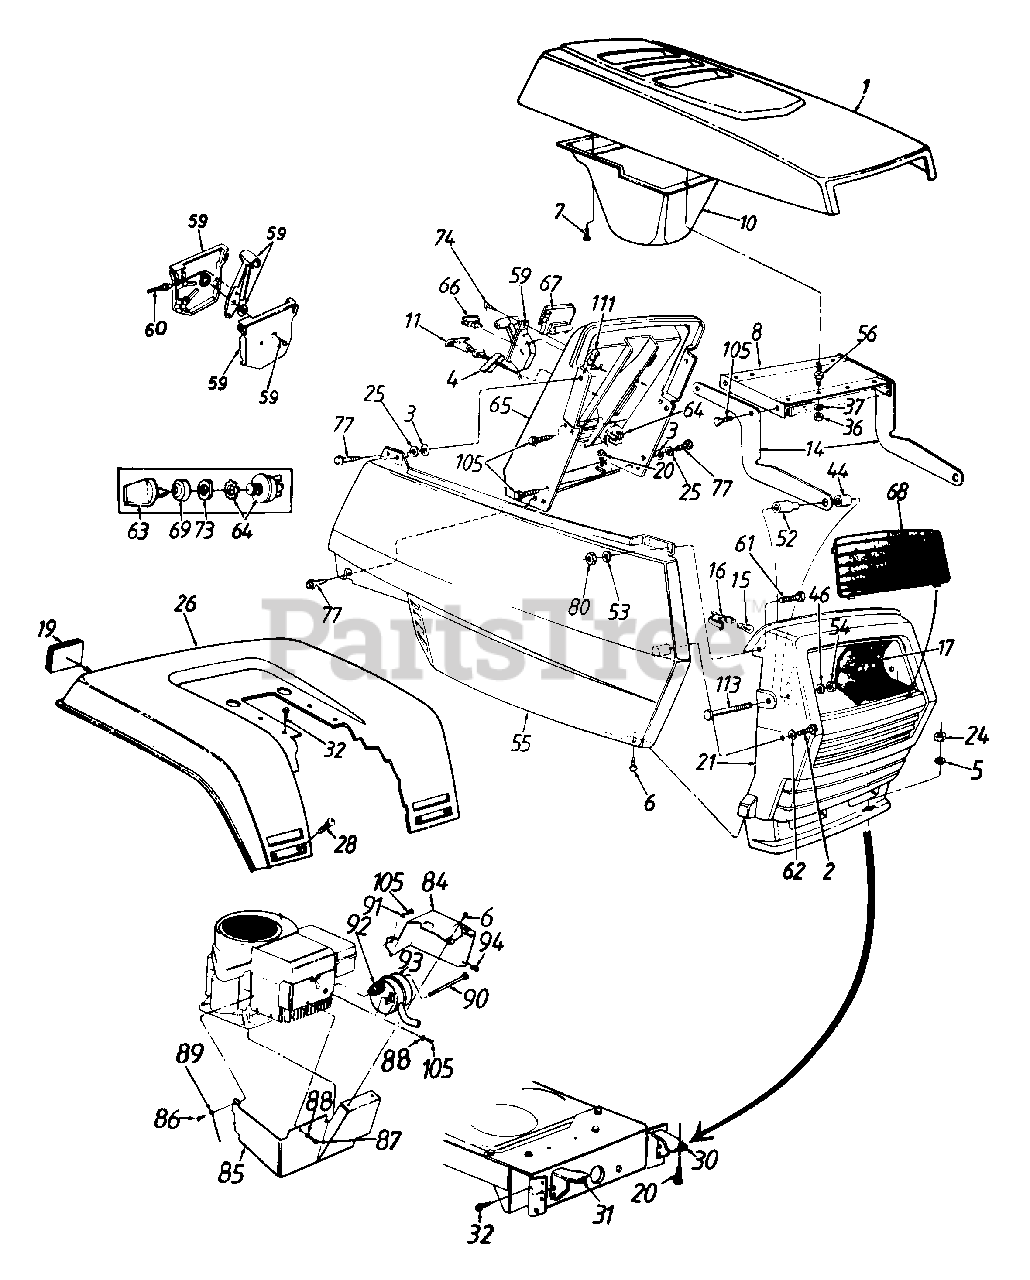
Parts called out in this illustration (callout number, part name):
1	Hood
2	Hex Wash. B-Tap Scr. 1/4 x .62" Lg.
3	Bolt Retainer 1/4" I.D.
4	Retainer Clip
5	Fl-Wash. .34" I.D. x .68"
6	Truss Mach. B-Tap Scr. #10 x .5" Lg.
7	Hex Wash Hd. AB-Tap Scr. #8 x .5" Lg.
11	Choke Control 29" Lg.
14	Hood Hinge
15	Lamp
16	Twist Lock - Lamp Socket
17	Reflector - Headlight
19	Reflector
20	Hex Bolt 5/16-18 x .75" Lg.
21	Grille
24	Hex Nut 5/16-18 Thd.
25	Fl-Wash. 1/4" I.D. x .93" O.D.
28	Carriage Bolt 1/4-20 x .5" Lg.
30	Grille Mount Brk't. - L.H.
31	Grille Mount Brk't. - R.H.
32	Hex Wash. Hd. AB-Tap Scr. 5/16 x .75" Lg.
36	Hex Nut 1/4-20 Thd.
37	Bell-Wash. .265" I.D. x .75"
44	Spacer .33" I.D. x .625" O.D.
46	Fl-Wash. .328" I.D. x .68" O.D.
52	Shld. Spacer .33" I.D.
53	Fl-Wash. .281" I.D. x .5" O.D.
54	Hex Cent. L-Nut 5/16-18 Thd.
55	Side Cover - R.H.
56	Double Ended Stud 1/4-20 Thd.
59	Throttle Control Box Ass'y.
60	Throttle Wire 18.5" Lg.
61	Hex Bolt 1/4-20 x .62" Lg.
62	Fl-Wash. .281" I.D. x .73" O.D.
64	Ignition Switch
66	Light Switch
67	Ammeter
68	Lens
69	Ignition Switch Cap
73	Ignition Switch Nut
74	Truss Mach. AB-Tap Scr. #10 x .5" Lg.
77	Hex Wash. Hd. Tap Scr. 1/4 x .75" Lg.
80	Hex L-Nut 1/4-20 Thd.
84	Muffler Heat Shield - L.H.
85	Muffler Heat Shield - R.H.
86	Pan Hd. Mach. Scr. 5/16-18 x .75" Lg.
87	Hex Bolt 1/4-20 x 3/8" Lg.
88	Spr. Wash. .265" I.D.
90	Shld. Bolt 7/16" Dia. x 3-5/8" Lg.
91	L-Wash. 1/4" I.D.
92	Gasket
93	Muffler
94	Speed Nut #10-24 Thd.
105	Hex Tap Scr. 1/4-20 x .5" Lg.
111	Speed Nut 1/4-20 Thd.
113	Hex Bolt 5/16-18 x 2.75"
